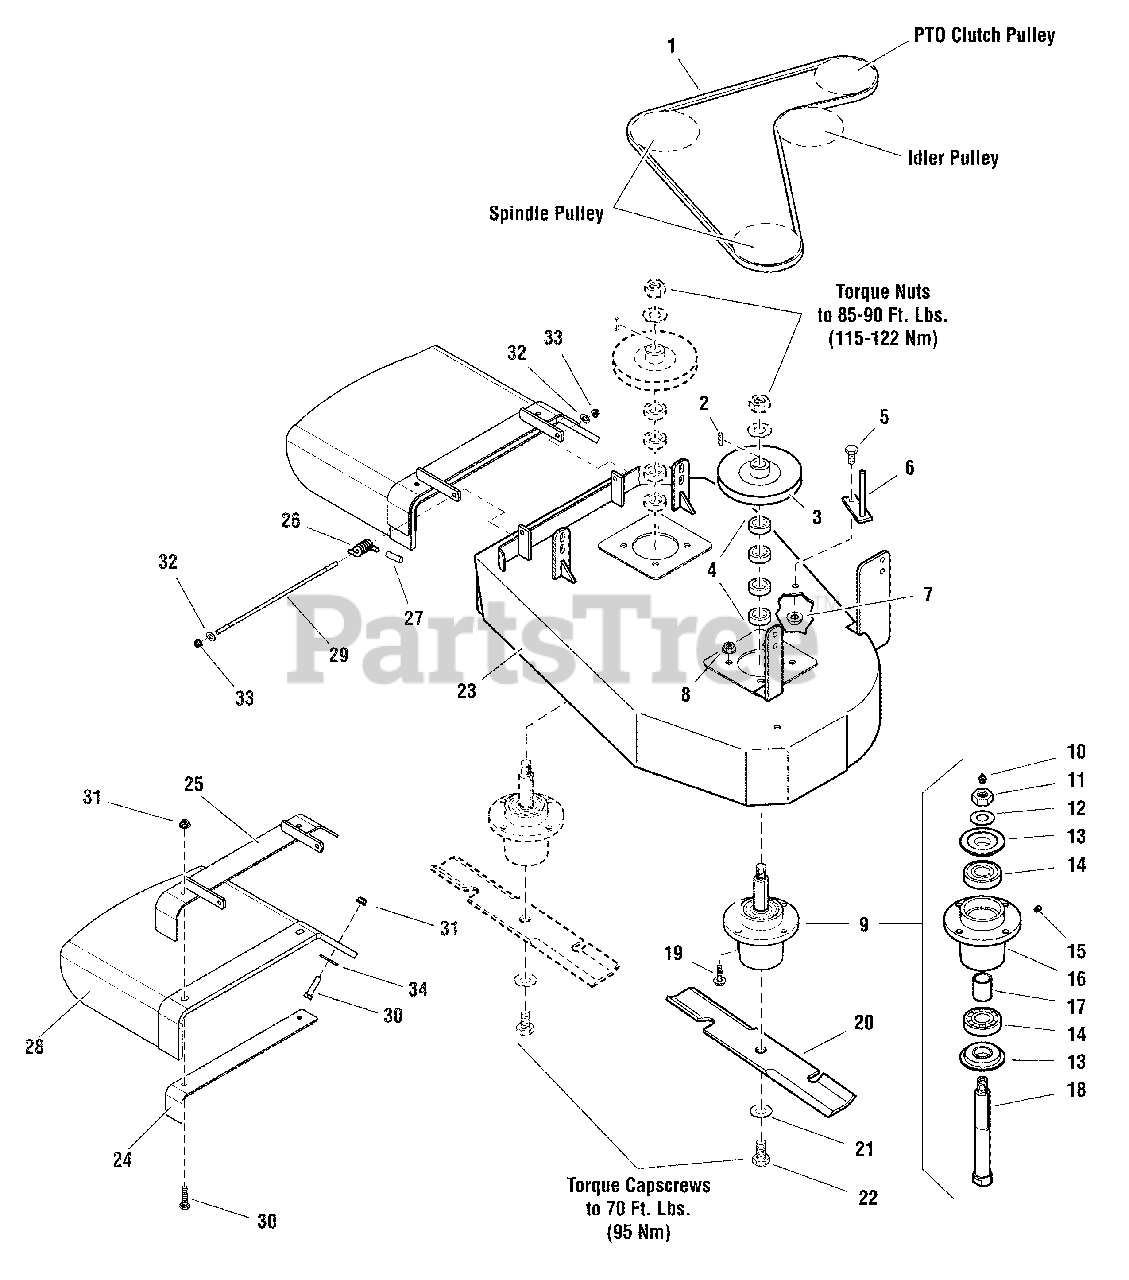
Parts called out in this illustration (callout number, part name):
1	BELT, #7-7169
2	KEY, 1/4 SQ. X 1.00
3	PULLEY, SPINDLE
4	SPACER, 1.02 X 1.56 X .50
5	BOLT, 3/8-16 X 1 GD5 YZ
6	WELD, BELT GUIDE - ORG
7	NUT, 1/4-20 HEX SERR. FLANGE
8	NUT, 5/16-18 HEX NYLOCK FLANGE
9	ASSM, SPINDLE, LONG SHAFT
10	GREASE FITTING
11	NUT, 3/4-16 HEX
12	WASHER, 3/4 BELLEVILLE
13	TRASH SHIELD
14	BEARING, .98 X 2.44 X .67
15	FITTING, RELIEF, 1-5 PSI
16	HOUSING, SPINDLE
17	SPACER, 1.00 x 1.25 x 1.75
18	SHAFT, SPINDLE
19	BOLT, 5/16-18 X 1 1/4 FLANGE
20	BLADE, 16.25
21	WASHER, 5/8 GRADE 8, YZ
22	BOLT, 5/8-11 X 1-3/4 GD8
23	WELD, MOWER DECK, 32" - ORG
24	BRACKET, CHUTE SUPPORT - BLK
25	WELD, CHUTE BRACKET - ORG
26	SPRING-TORSION CHUTE 44/50" BLK
27	CAP-SPRING END .093ID .75 LG BLACK VINYL
28	RUBBER DISCHARGE CHUTE, S50X-36 OFFSET
29	ROD, CHUTE PIVOT
30	BOLT, 3/8-16 X 1-1/2 GD5 YZ
31	NUT, 3/8-16 HEX NYLOCK FLANGE
32	WASHER, 5/16 SAE
33	NUT, 5/16-24 HEX NYLON LOCK
34	WASHER, .390 X 1.50 X .109, YZ
